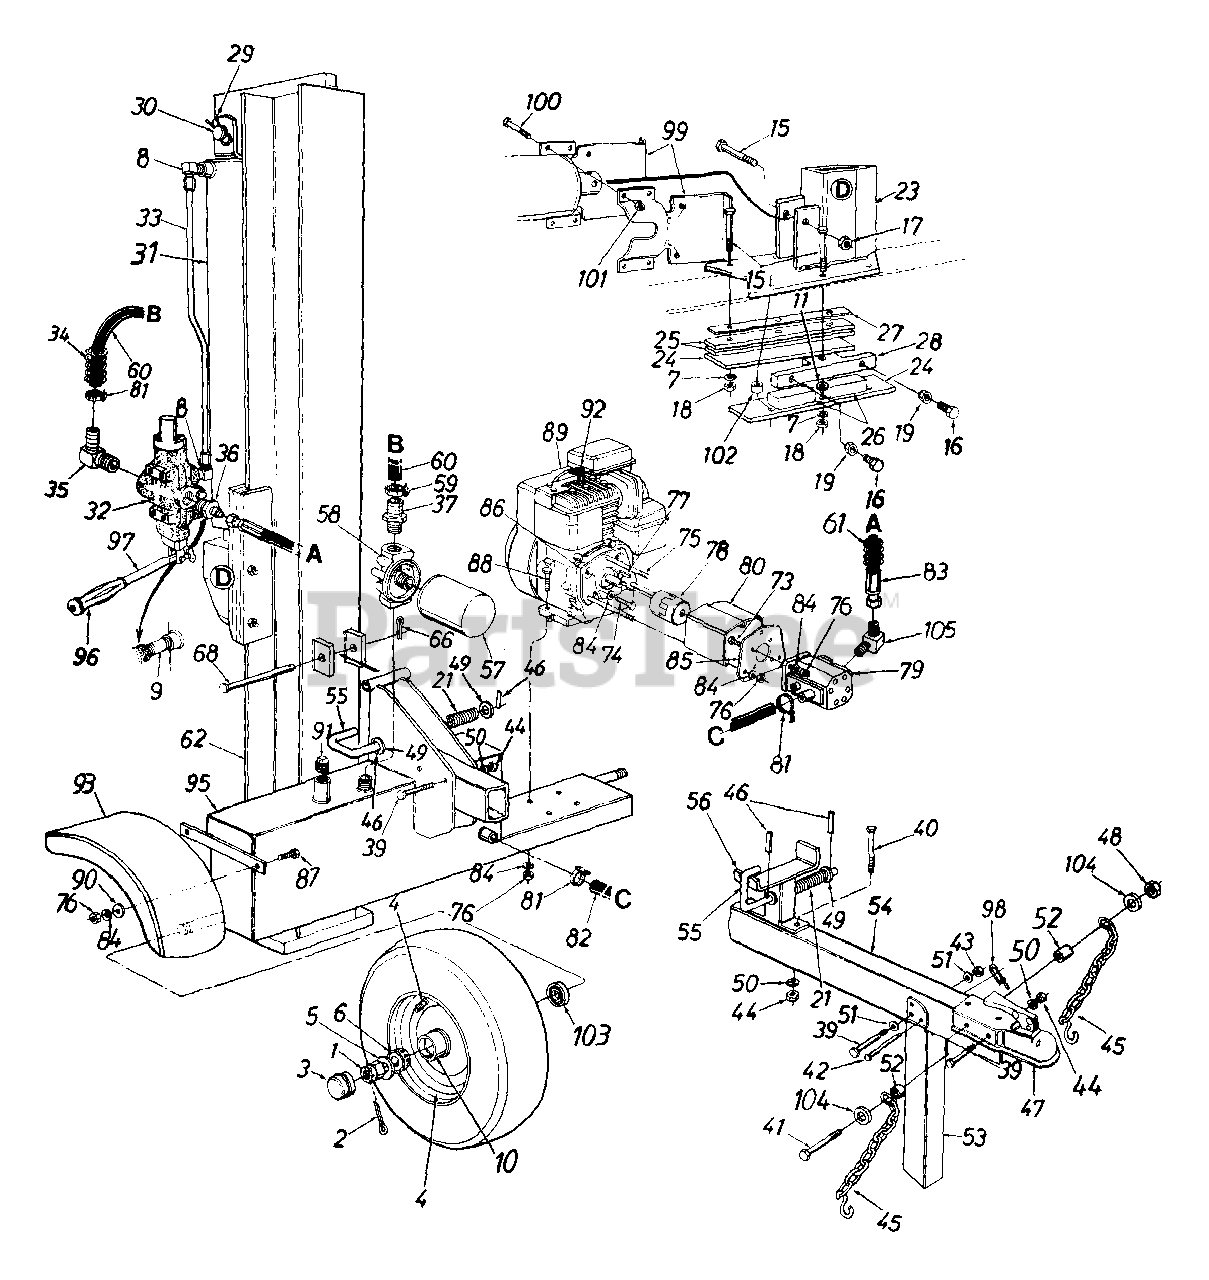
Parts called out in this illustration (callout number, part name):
1	Slotted Nut 3/4-16 Thd.
2	Cotter Pin 5/32" Dia. x 1-1/4" Lg.
5	Fl-Wash. .76" I.D. x 1.5" O.D.
6	Bearing Cone
7	L-Wash. 1/2" I.D.
8	90ø Solid Male Adapter
9	Pipe Nipple 1/2 NPT
10	Bearing Cup
11	Fl-Wash. .531" I.D. x .94" O.D.
15	Hex Bolt 1/2-20 x 2.75" Lg. (Grade 8)
16	Hex Bolt 3/8-24 x 1.5" Lg.
17	Hex L-Nut 1/2-20 Thd.
18	Hex Nut 1/2-20 Thd.
19	Hex Jam Nut 3/8-24 Thd. (Grade 5)
21	Comp. Spring 4" Lg.
26	Adjustable Gib
29	External Cotter Pin
30	Cylinder Mounting Pin
33	Metal Pressure Tube
34	Hose Guard
35	Return Elbow
37	3/4" Hose Barb.
39	Hex Bolt 3/8-16 x 2.75" Lg. (Grade 8)
40	Hex Bolt 3/8-16 x 4" Lg.
41	Hex Bolt 3/8-16 x 4" Lg. (Grade 5)
42	Clevis Pin 5/16 x 2.5" Lg.
43	Hex L-Nut 3/8-16 Thd.
44	Hex Nut 3/8-16 Thd.
45	Chain - Tow Hitch
47	Hitch Coupler
48	Hex Ctr. L-Nut 3/8-16 Thd.
49	Fl-Wash. .635" I.D. x .93" O.D.
50	L-Wash. 3/8" I.D.
51	Fl-Wash. .406" I.D. x .75" O.D.
52	Spacer 3/8" I.D. x .625" O.D.
57	Filter Element
58	Filter Head
59	Hose Clamp 5/8"
60	Return Hose 3/4" I.D. x 44" Lg.
61	Hose Guard
68	Hinge Pin 1/2 x 4.8" Lg.
73	Hex Bolt 5/16-24 x 1" Lg.
74	Hex Bolt 5/16-24 x .62" Lg.
75	Hex Bolt 5/16-24 x 4" Lg.
76	Hex Nut 5/16-24 Thd.
77	Sq.-Key 3/16" x .75"
78	Flexible Coupling
79	Gear Pump
80	Coupling Shield
82	Suction Hose
83	High Pressure Hydraulic Hose
84	L-Wash. 5/16" I.D.
87	Hex Bolt 5/16-24 x .75" Lg.
88	Hex Bolt 5/16-24 x 1.75" Lg.
89	Engine
90	Fl-Wash. .344" I.D. x .875" O.D.
91	L-Vent Pipe Plug
92	Spark Plug Boot
97	Control Handle
101	Hex L-Nut 3/8-16 Thd.
102	Spacer 1/2" I.D. x .68" Lg.
103	Bearing Seal Only
104	Fl-Wash. 3/8" I.D. x .87" O.D.
105	90ø Male Adapter
